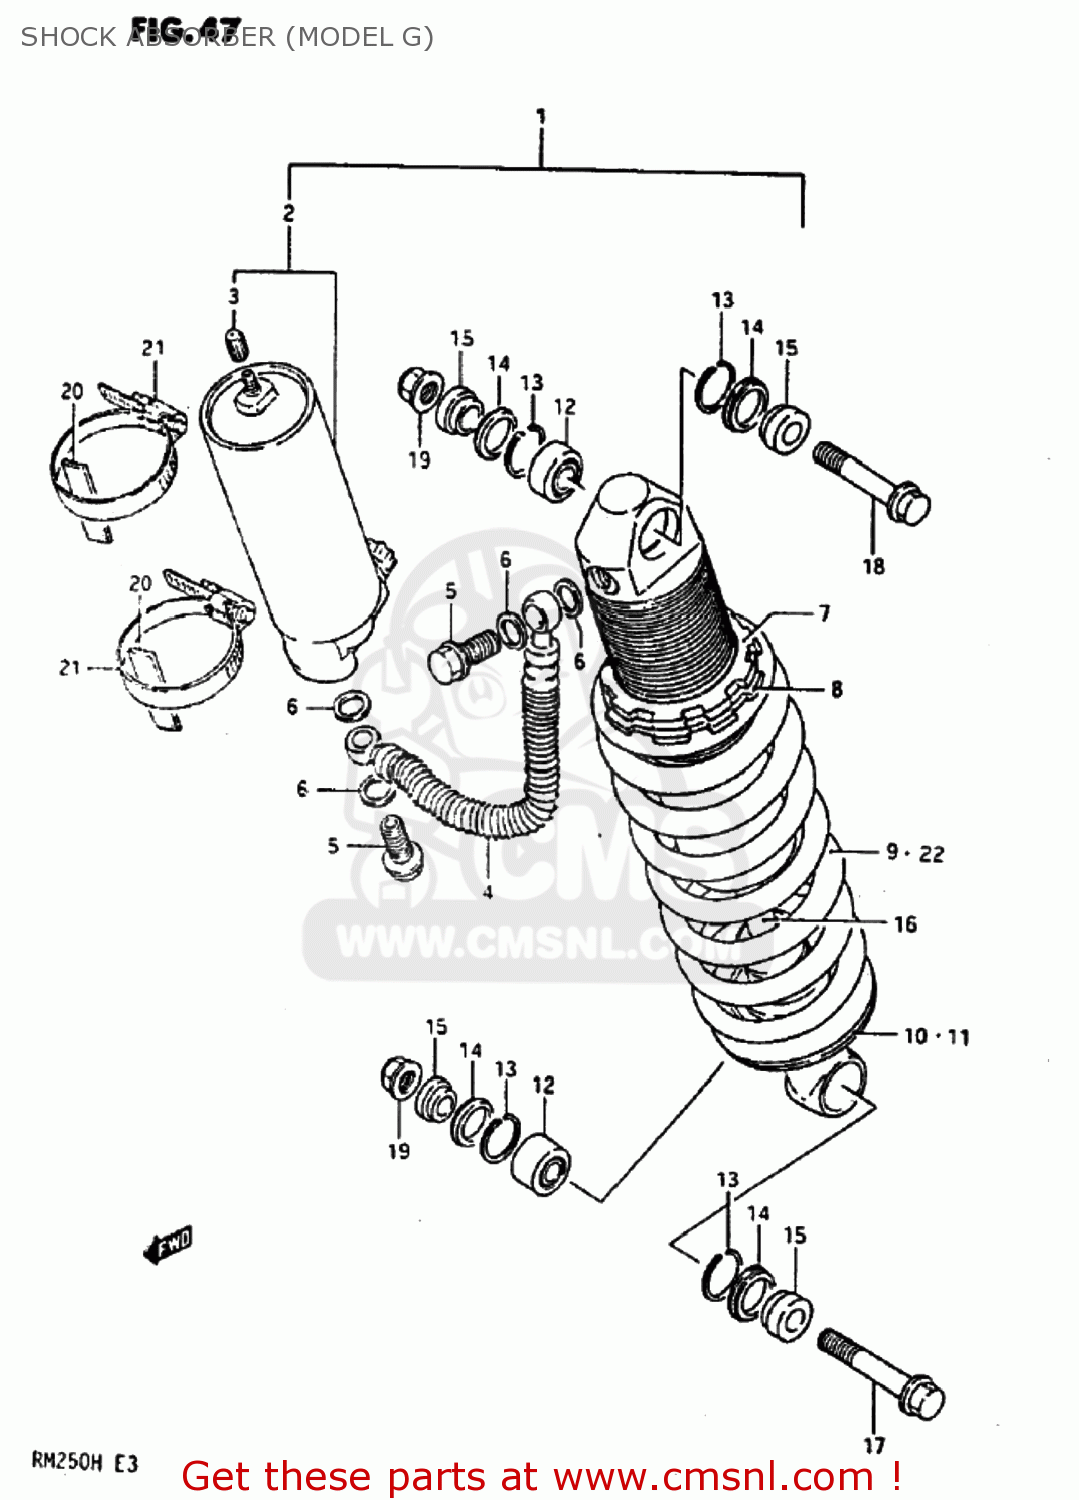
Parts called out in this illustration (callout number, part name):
1	ABSORBER ASSEMBLY,REAR SHOCK
2	TANK
3	CAP
4	HOSE
5	BOLT,REAR SHOCK ABSORBER
6	GASKET (NAS)
7	NUT
8	GUIDE,SPRING
9	SPRING
10	WASHER
11	GUIDE,SPRING
12	BEARING,REAR SHOCK ABSORBER
13	RING
14	SEAL,DUST RR SHOCK ABSORBER
15	COLLAR
16	ROD,PISTON
17	BOLT,REAR SHOCK ABSORBER
18	BOLT,UPPER
19	NUT
20	CUSHION,REAR SHOCK ABSORBER
21	CLAMP
22	SPRING,REAR (SOFT)
